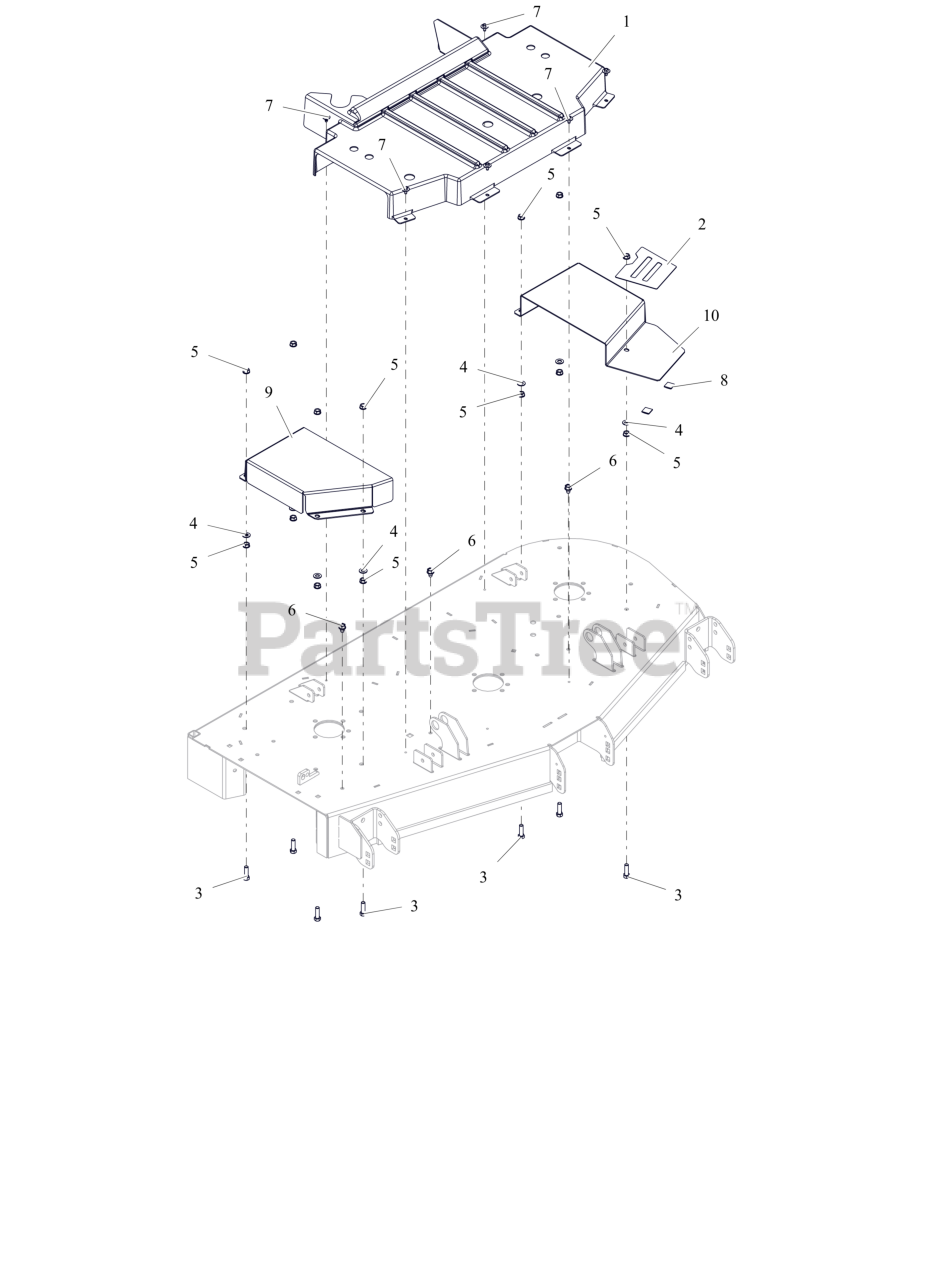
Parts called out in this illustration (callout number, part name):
1	GUARD,CENTER,DECK SPINDLE CE
2	GRIP TAPE 52-60 BELT COVER
3	BLT, HEX .38-16X1.25 G5 ZCC
4	WSHR,FLT .406X.812X.065 ZCC
5	NUT, SPNLK-FLG .38-16 G5 ZCC
6	SCR,TAP .375-16X.50 HWH TR ZCC
7	SCR, TAP .25-20X.50 LG HWH ZCC
9	GUARD, BELT 52" RIGHT CE (ORANGE)
10	GUARD, BELT 52" LEFT CE (ORANGE)
